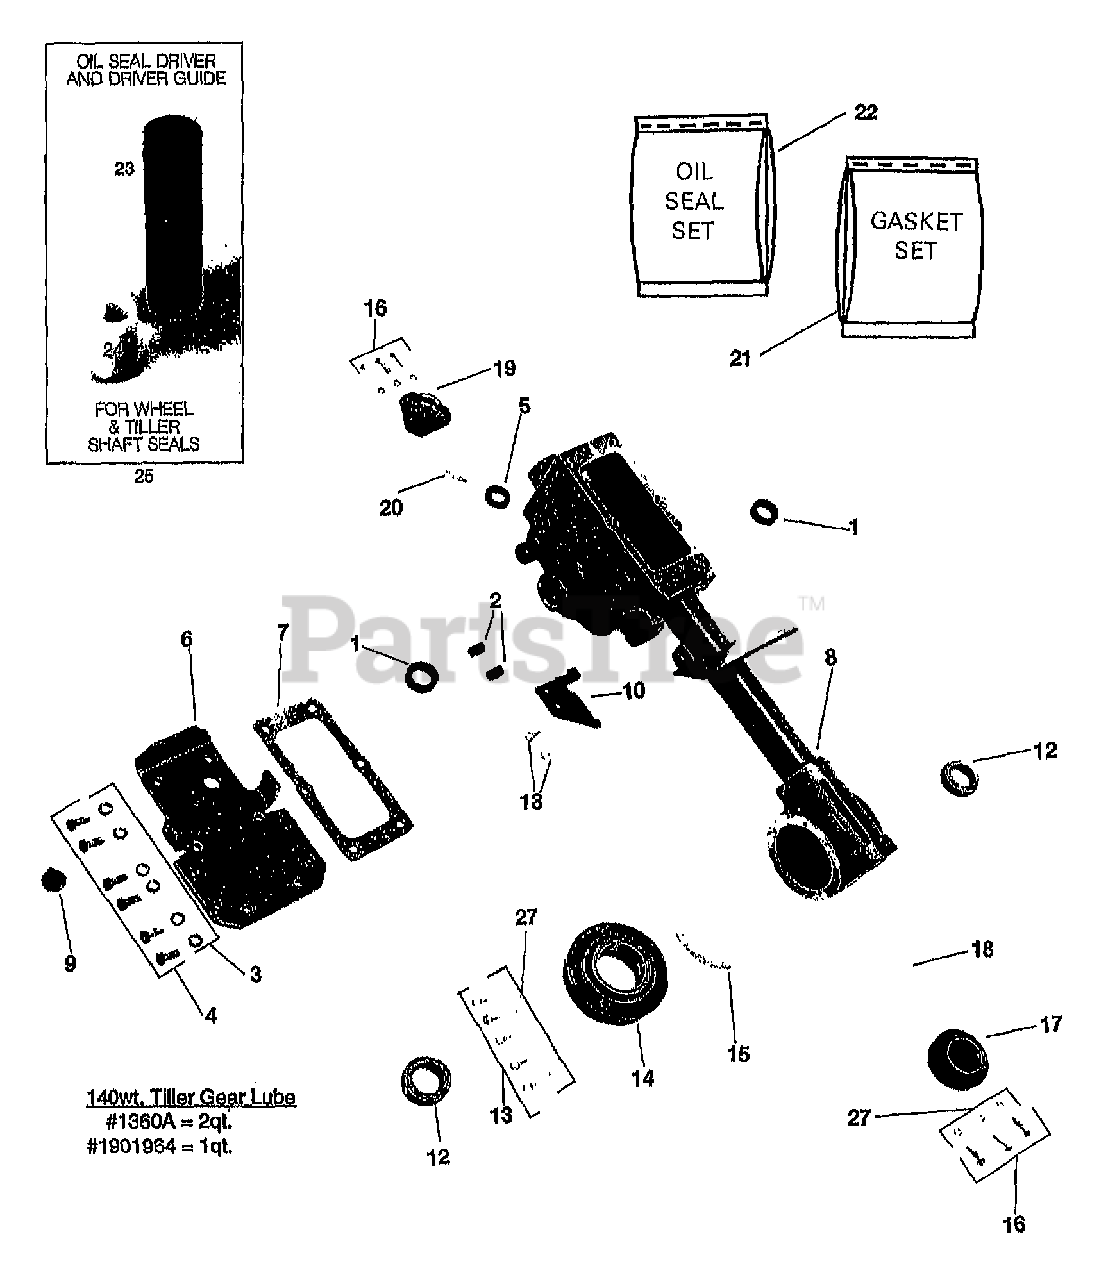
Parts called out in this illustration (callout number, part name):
1	SEAL-OIL WHEELSHAFT
2	PLUG-PIPE 1/4 NPT
3	WASHER-LK .312 ZP
4	SCR-HHC 5/16-18X.75 GR 5 ZP
5	SEAL-PINION SHAFT PT/85030/00
6	COVER-TRANS
7	GASKET-TRANS COVER
8	HSG-TRANS P5 A UNIT (INCL. ONE #9429 REAR BEARING RACE)
9	PLUG-OIL FILL 3/4-10
10	PLATE-CABLE MOUNT PNT (FOR WHEEL DRIVE CABLE)
12	SEAL-TILLER SHAFT
13	SCR-HH 1/4-20X.625
14	COVER-RTH W/SCRS&RACE
15	GASKET-TILLER COVER
16	SCR-HFLK 1/4-20X.875
17	CAP-REAR #1115
18	GASKET-BRG COVER
19	COVER-FRONT BEARING
20	GASKET-FRONT COVER-.010
21	GASKET SET-P4
22	OIL SEAL SET-PONY V
23	DRIVER-PLASTIC (USE WITH PART #4921-2)
24	SEAL-DRIVER PILOT (USE WITH PART #4921-1)
25	KIT-DRIVER (INCL. 23, 24)
27	WASHER - NYLON, NOT REUSABLE
